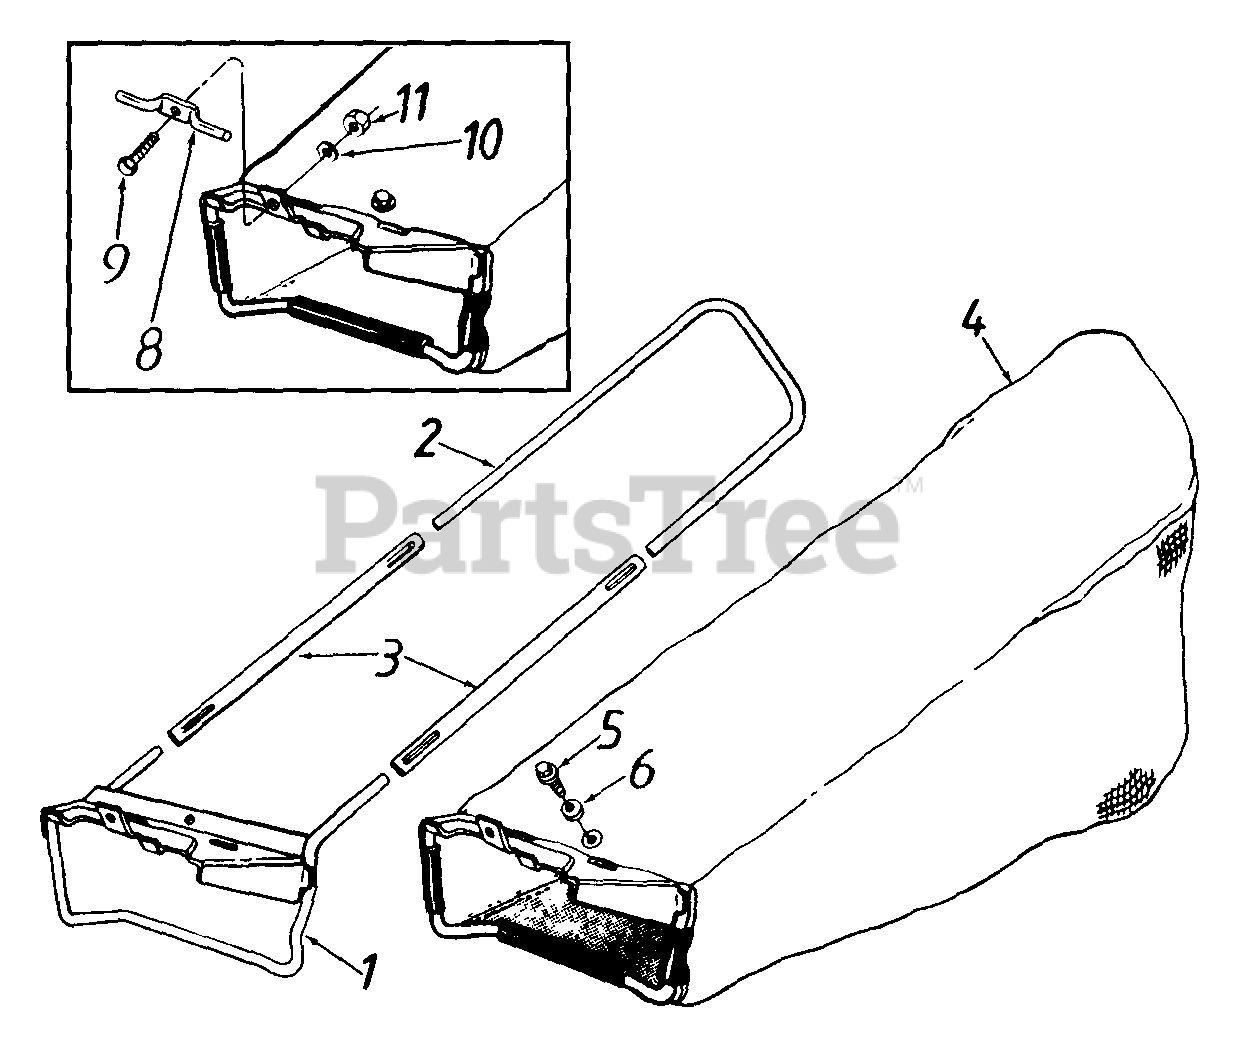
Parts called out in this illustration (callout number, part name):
4	Grass Bag
5	Hex Wash. Hd. TT-Tap Scr 1/4-20 x 5" Lg.
6	Bell-Wash 1/4" I.D.
8	Grass Bag Hook
9	Hex Bolt 1/4-20 x 62" Lg
10	L-Wash. 1/4" I.D.
11	Hex Nut 1/4-20 Thd.
